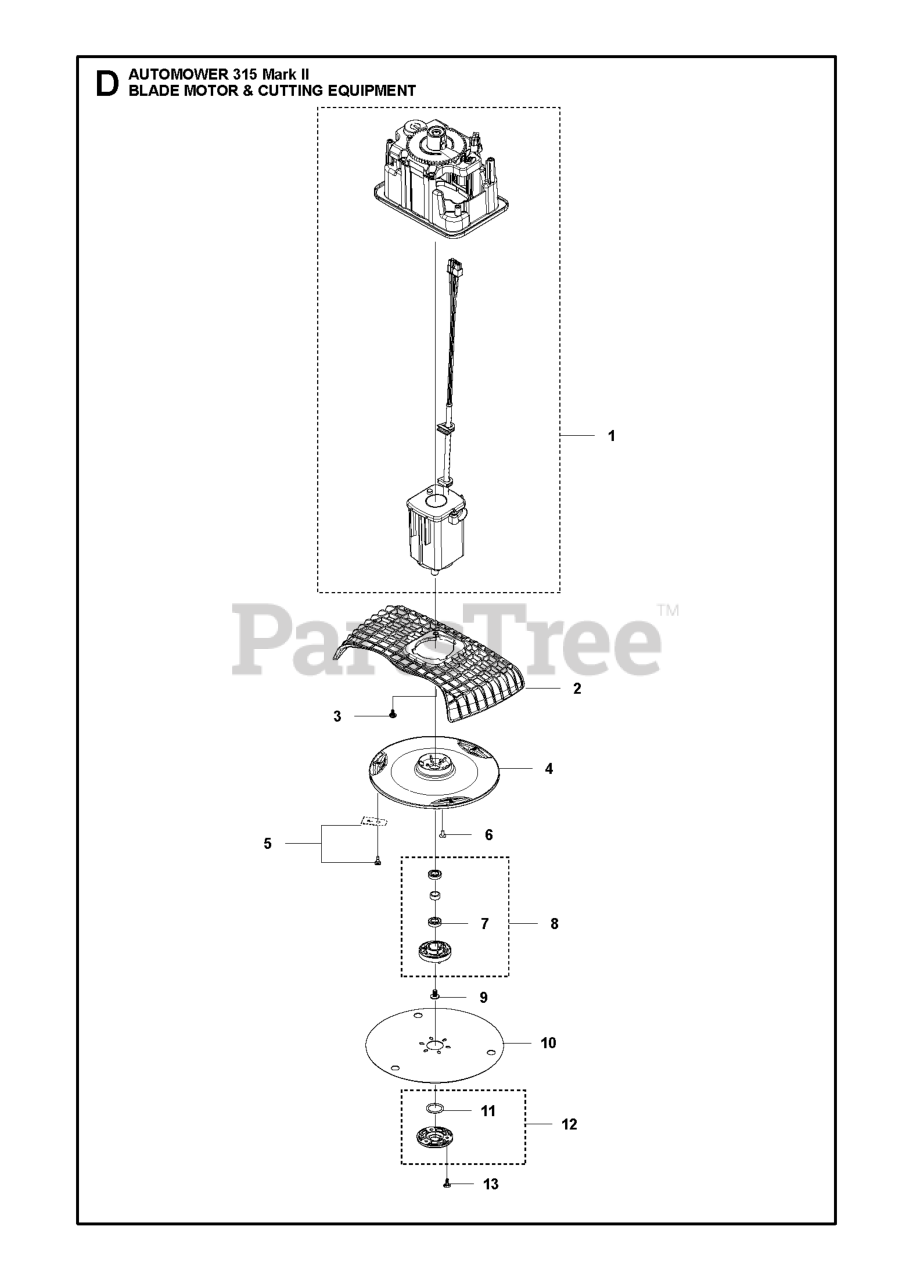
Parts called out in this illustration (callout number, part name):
3	SCREW ITXPANT
4	CUTTING DISC
6	SCREW HEXAGON SOCKET BUTTON HE
7	BALL BEARING 2 RS,TIGHT CLEAR
7	BALL BEARING BALL BEARING 535
8	BEARING HOUSING ASSY
11	O-RING 20X2,5 MM
12	COVER KIT BEARING
13	SCREW 14MM
